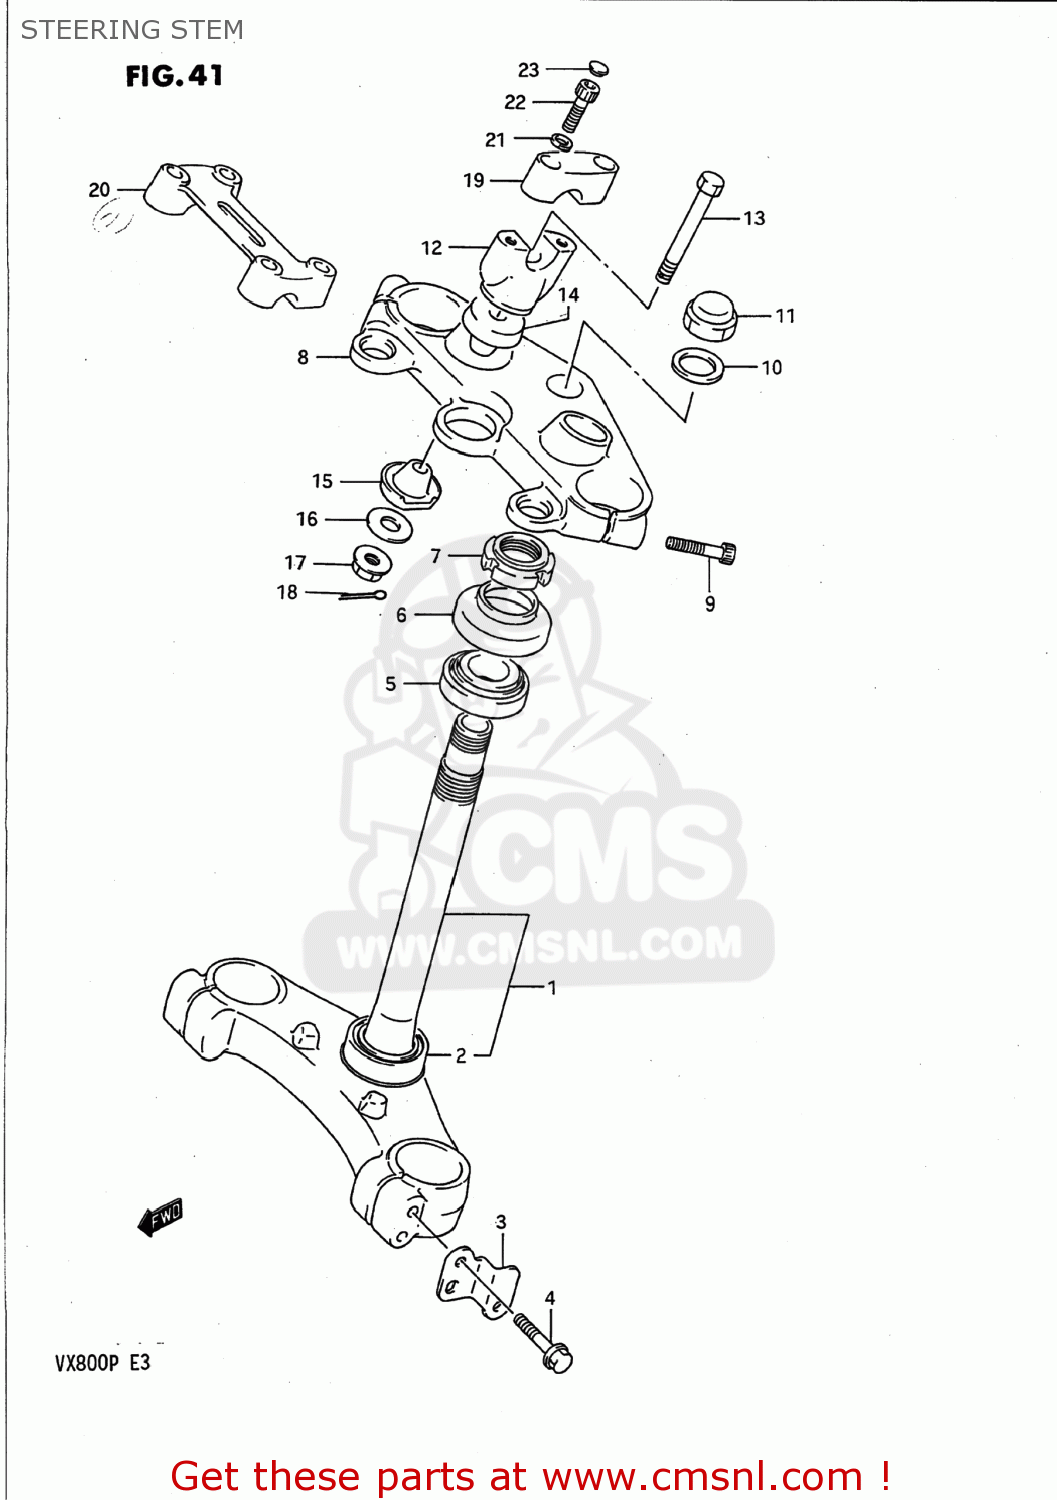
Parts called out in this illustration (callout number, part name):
1	STEM,STEERING
2	BEARING(30X55X17)
3	BRACKET,SIDE REFLECTOR
4	BOLT,STEM HEAD(8X40)
5	TAPER,ROLLER BEARING
6	DUST SEAL,STEERING,UPPER
7	NUT,STEERING STEM(25X44X10)
8	HEAD,STEERING STEM
9	BOLT, LH
10	WASHER(22.5X32X1.6)
11	NUT,CAP
12	HOLDER,HANDLE LWR
13	BOLT
14	RUBBER,DAMPER
15	DAMPER,LWR
16	WASHER,HANDLEBAR HOLDER
17	NUT
18	COTTER PIN
19	HOLDER,HANDLEBAR
20	HOLDER,HANDLE UPR
21	WASHER
22	BOLT, LH
23	CAP(OD:14.5)
